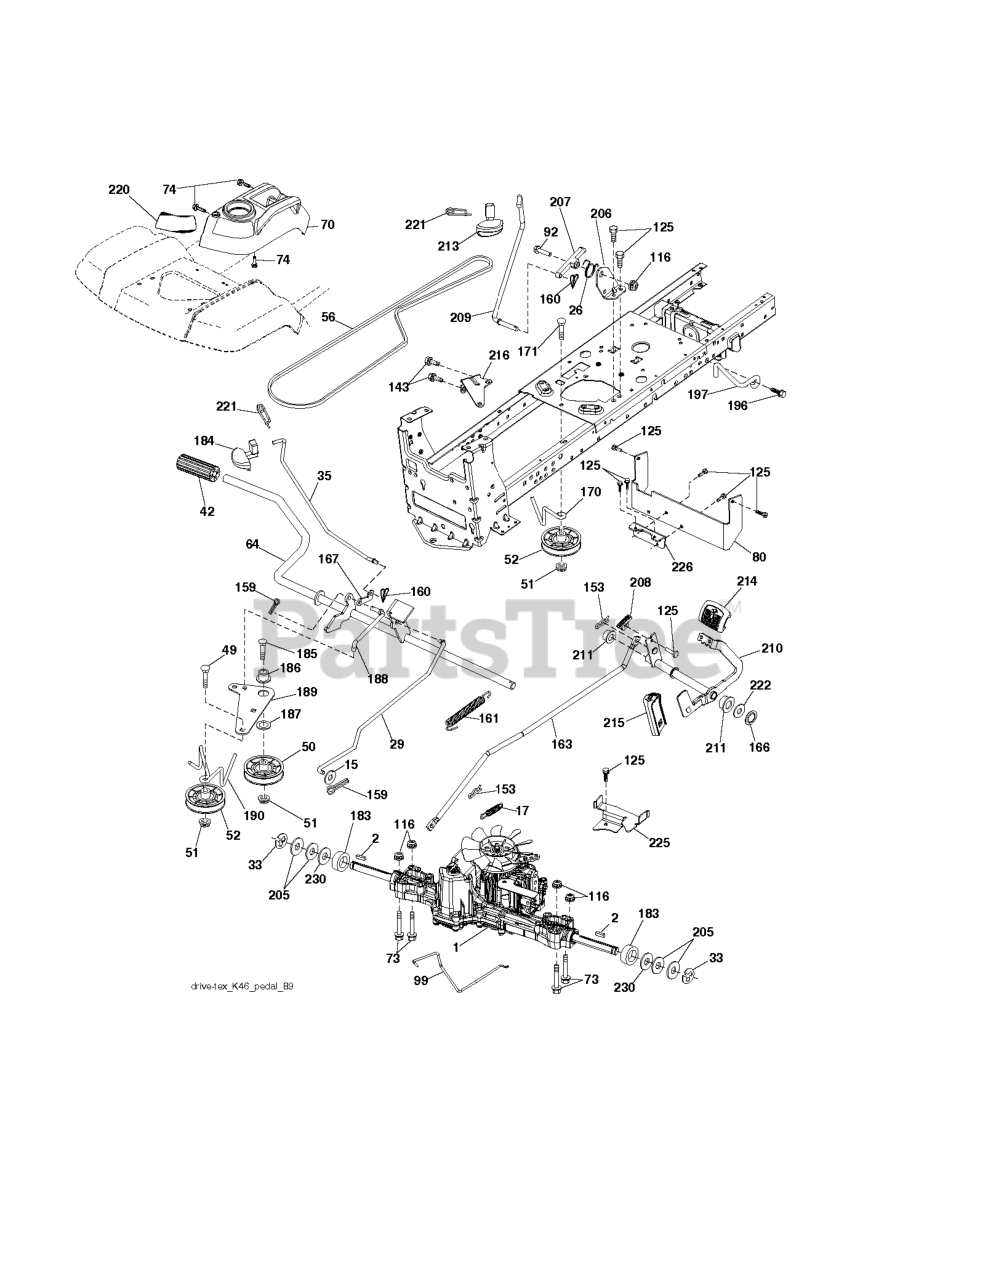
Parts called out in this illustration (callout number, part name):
1	TRANSAXLE(K46BT).PDL.
2	SQUARE KEY
15	WASHER
17	SPRING.BRAKE.K46.GREEN
26	SPRING.RETURN.CRUISE
29	ROD.BRAKE.K46
35	ROD.BRAKE.PARKING.GT.H
42	PEDAL COVER T
50	IDLER.FLAT.910.OFFSET
51	NUT LOCK FLG 3/8-16 UNC
52	IDLER.V-GROOVE.910.OFFSET
56	V-BELT.MOWER.92.40.42/K46
64	SHAFT.ASM.PEDAL.BRK.CNTR
70	RP CONSOLE.ASM.PCH.W/TB
73	BOLT
74	SCREW.HI-LO.CONSOLE
80	STRAP TORQUE
92	BOLT
99	ROD.SPRING.BYPASS.K46.LT.Z
116	NUT LOCK HEX FLANGE 5/16-18
125	SCREW
143	SCREW LT
153	RETAINER M
159	COTTER PIN
160	RETAINER CLIP
161	SPRING, RETURN LT
163	ROD.CONTROL.PEDAL.K46
166	NUT.PUSH.625
167	LATCH.BRAKE.SPRING
170	KEEPER.V-IDLER.CENTER.
171	BOLT
183	SPACER AXLE
184	HANDLE.PARKG.BRK.HUSQ X667
186	SPACER.RETAINER
187	WASHER 12/32X2X10GA
188	RP.LINK.CLUTCH.GROUND.DRIVE
189	BELLCRANK.GROUND.DRIVE.TEX.
190	KEEPER.BELLCRANK.DRIVE
196	SCREW 3/8-16X1
197	LINK.CLUTCH.ANIT-ROTAT
206	BRKT.MOUNT.LATCH.CRUIS
207	LATCH.CONTROL.CRUISE
208	GEAR.SECTOR.CONTROL.CR
209	ROD.CONTROL.CRUISE.GT.
210	ROCKER.ASM.PEDAL.CONTR
211	BEARING.NYLON
213	KNOB.CONTROL.CRUSIE.HU
214	PEDAL.FORWARD.PAD.TEX
215	PEDAL.REVERSE.TEX.GT.4
216	BRACKET.PULLEY.IDLER.W/TEX
220	REFLECTOR.RH.TEX GT
221	RETAINER.SPRING.CLIP.H
222	WASHER 21/32 X 1-1/4 X 10 GA.
225	KEEPER.BELT.TRANSAXLE.K46
226	BRACKET.MOUNT.TORQUE.K46.TLT
230	WASHER.HARDENED
